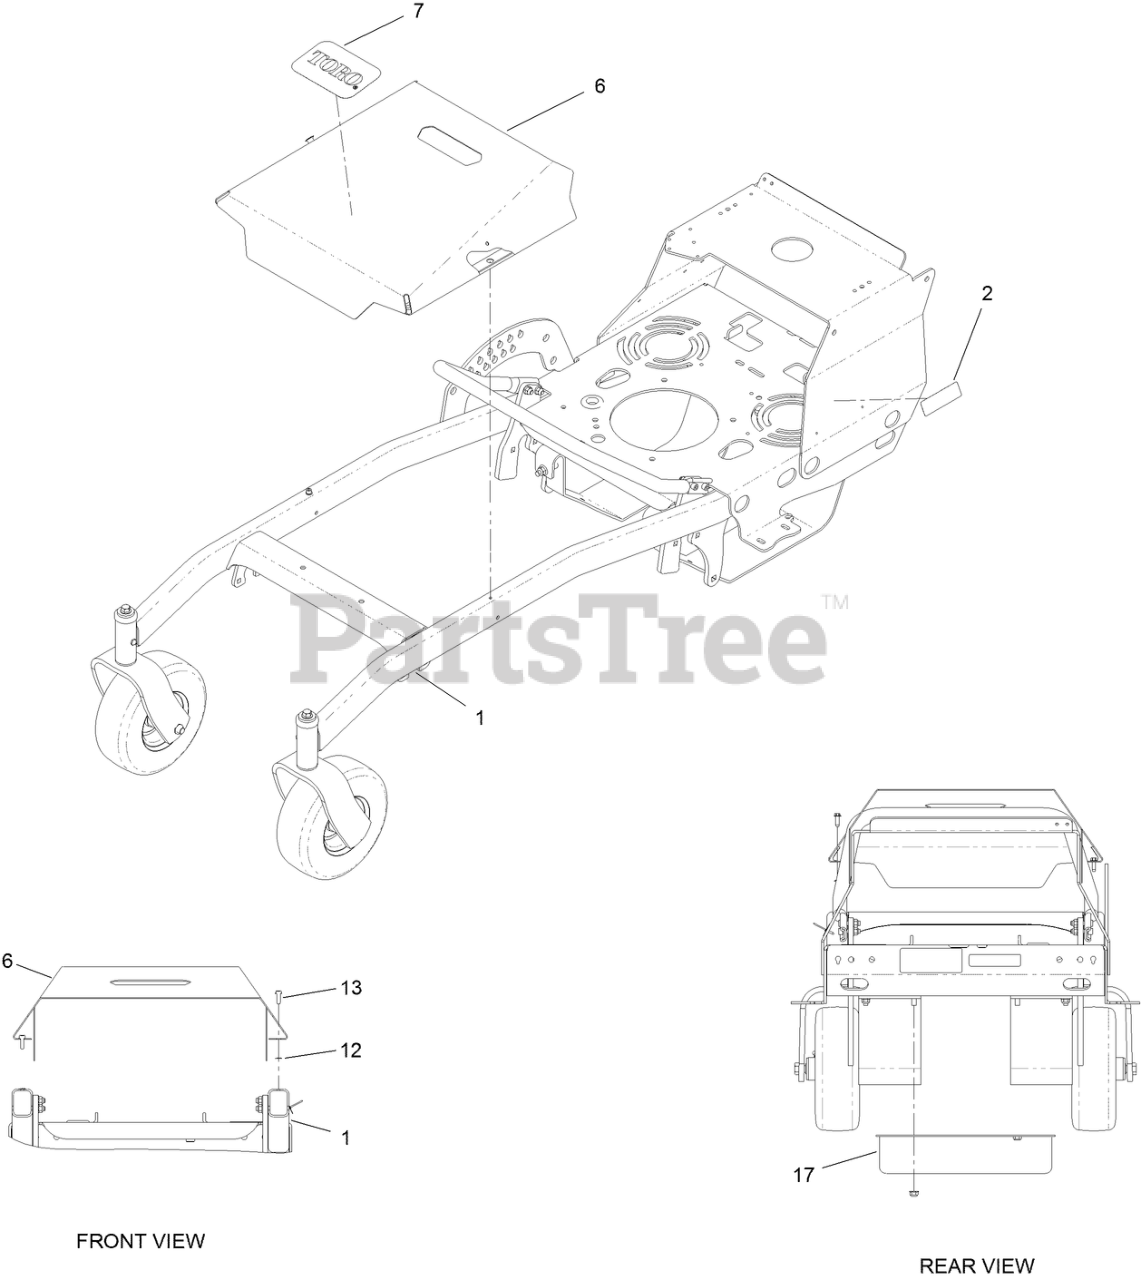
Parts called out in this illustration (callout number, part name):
1	FRAME ASSEMBLY
2	DECAL-EMISSIONS, EXPORT
6	COVER-DECK
7	DECAL
12	NUT-RETAINING
13	SCREW-HWHTF
17	PLATE-GUARD, INTL
